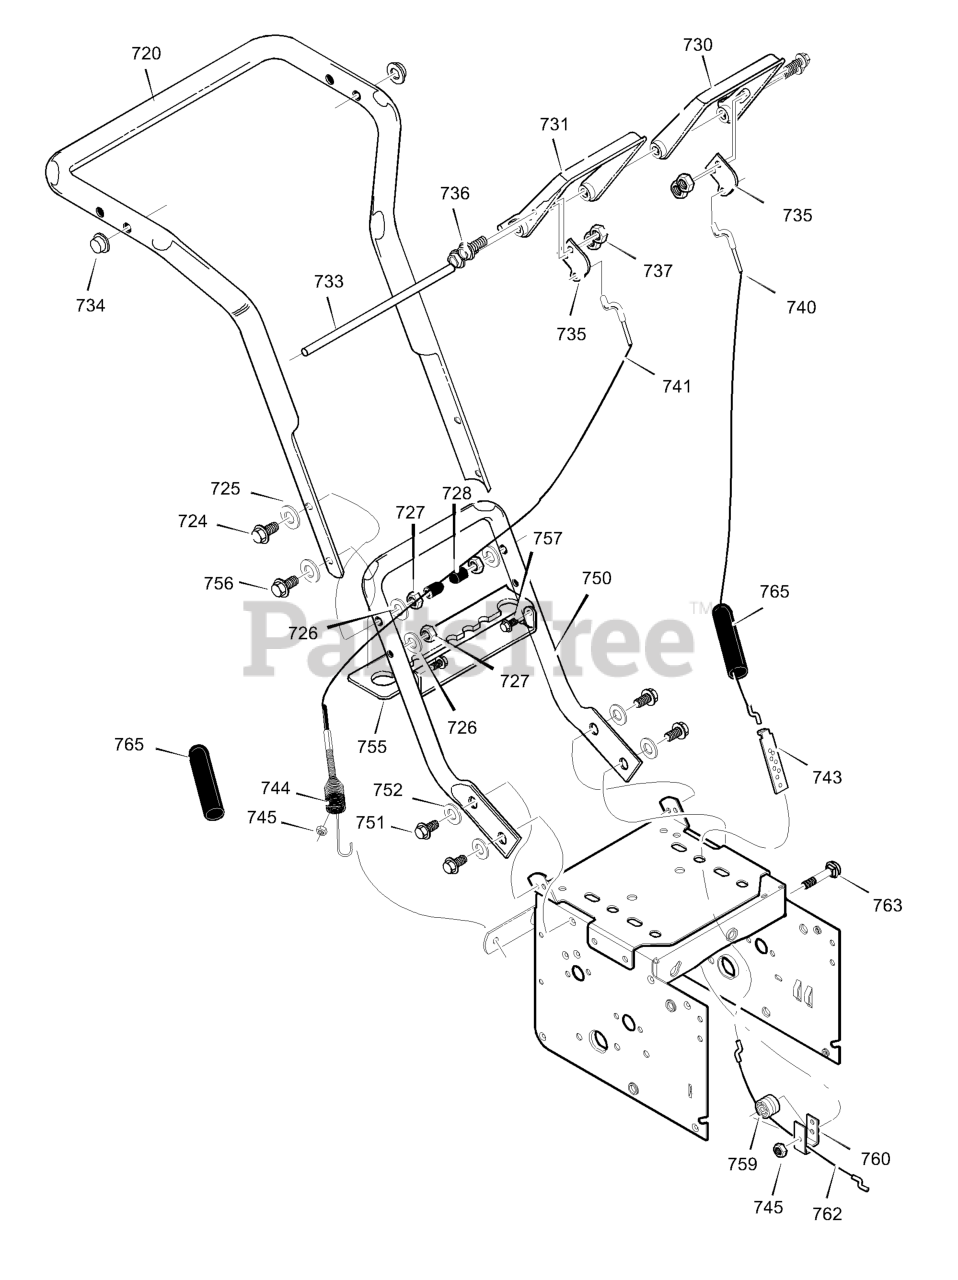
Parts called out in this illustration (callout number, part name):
724	SCREW, 5/16-18 x 2.75
725	WASHER, FLAT
726	WASHER, SPTLK
727	NUT, 5/16-18
728	PLASTIC-STOP
730	CLUTCH, LEFT HANDLE CONTROL
731	CLUTCH, RIGHT HANDLE CONTROL
733	ROD, PIVOT HANDLE
734	PUSH ON CAP
735	PLATE, CABLE PIVOT
736	SCREW, 1/4-20 x .88
737	NUT, 1/4-20
740	CABLE, DRIVE
741	CABLE, AUGER CLUTCH
743	BRKT, CABLE ADJUST
744	SPRING, AUGER CLUTCH
745	NUT, 1/4-20 HEX NYLOCK
750	HANDLE, LOWER
751	SCREW, 5/16-18 x 0.75
752	WASHER, SPTLK
755	BRACKET, GEAR SELECTOR
756	SCREW, 5/16-18 x 2.00
757	SCREW, 1/4-20 x .63
759	SPOOL-CABLE, AUGRT CLUTCH
760	BRACKET, CABLE SPOOL YZ
762	CABLE, LOWER DRIVE 12"
763	BOLT, HEX 1/4-20 X 1.50 YZ
765	BOOT, CLUTCH SPRING
